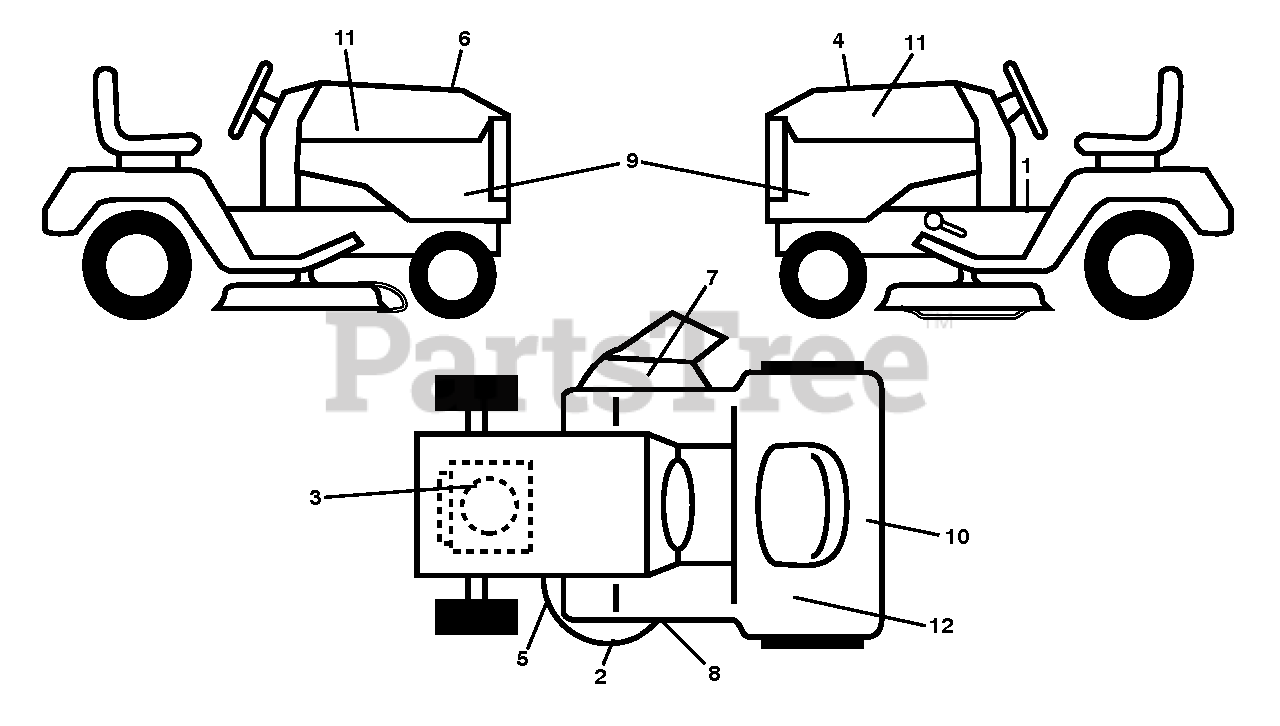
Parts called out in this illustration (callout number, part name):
1	DECAL.WARNING.2007.ENG/FR
2	DECAL.DECK.STAMP.BIOCLIPCMP.HU
3	DECAL.ENGINE.B&S
5	DECAL.MOWER.CAUTION.TENSION.AR
6	DECAL.ETHANOL.E85 WARNING SYMB
7	DECAL.DECK.DEFLECTOR.WARNING
8	DECAL.DECK.BELT.ROUTING.48/54
9	DECAL SIDE PANEL
11	DECAL.BADGE.170MM.TEXTLOGO.
12	DECAL.DECK.BUILTINAMERICA.HUSQ
